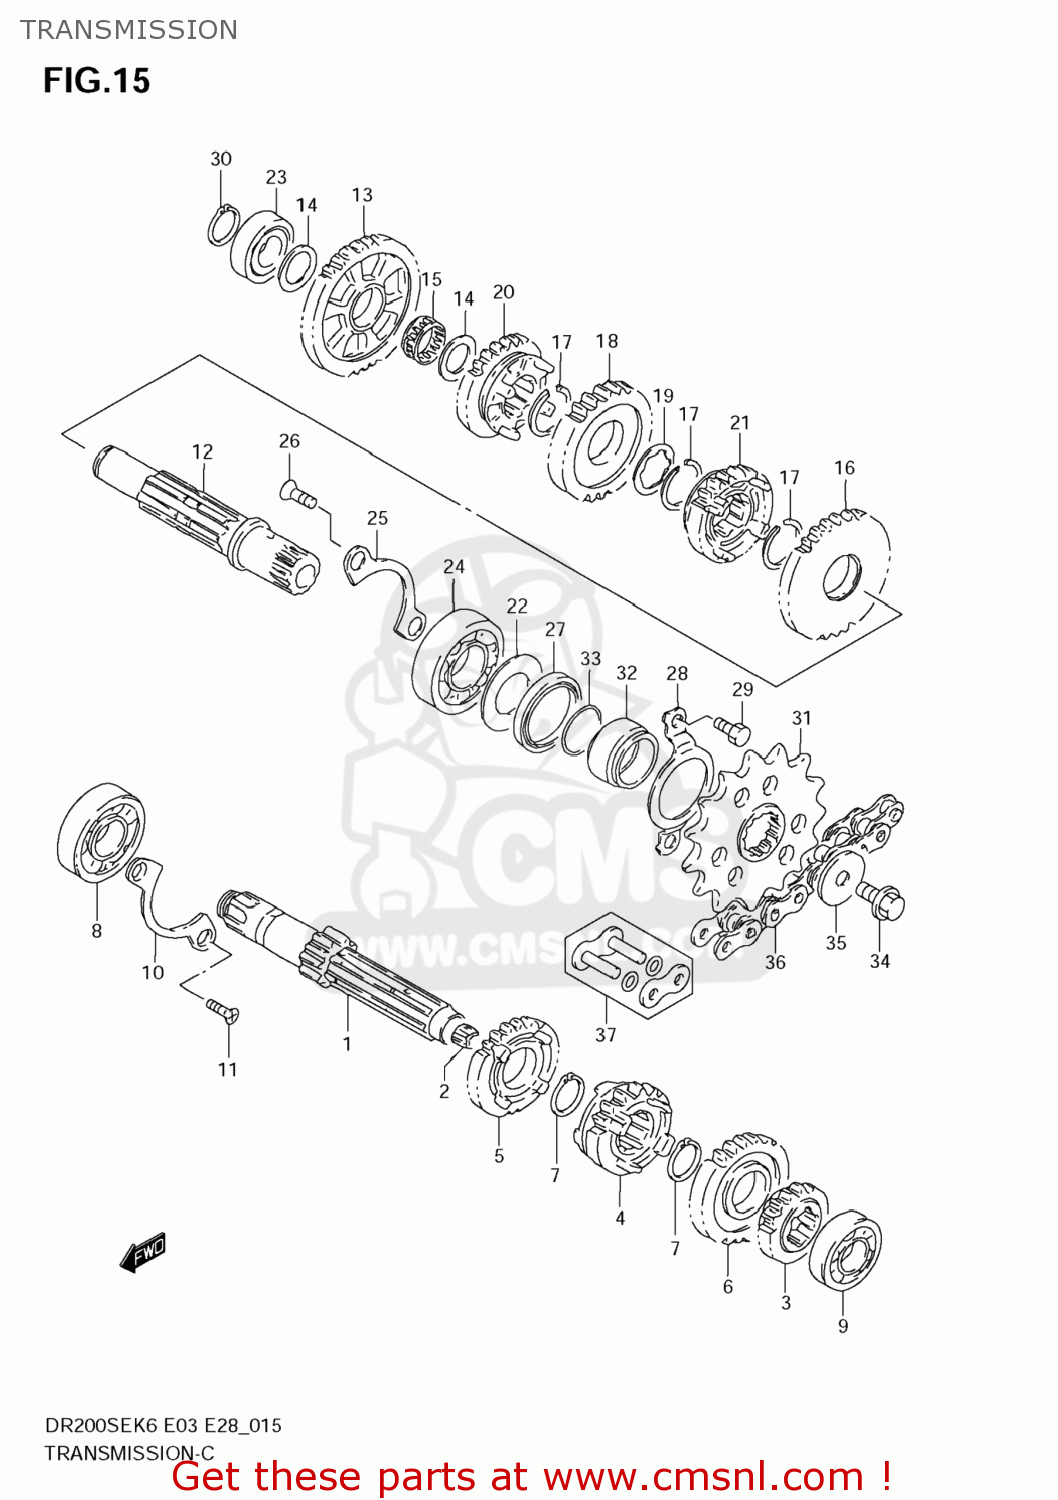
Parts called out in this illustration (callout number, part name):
1	SHAFT,COUNTER
2	BUSH
3	GEAR,2ND DRIVE
4	GEAR,3RD DRIVE(NT:16)
5	GEAR,4TH DRIVE
6	GEAR,FIFTH DRIVE
7	CIRCLIP
8	BEARING(20X47X14)
9	BEARING
10	RETAINER,DRIVE SHAFT BEARING
11	SCREW
12	SHAFT,DRIVE
13	GEAR,1ST DRIVEN
14	SHIM(17X26X1)
15	BEARING(17X21X9.8)
16	GEAR,2ND DRIVEN(NT:29)
17	CIRCLIP
18	GEAR,3RD DRIVEN(NT:23)
19	WASHER,LOCK
20	GEAR,4TH DRIVEN(NT:23)
21	GEAR,5TH DRIVEN
22	WASHER,OIL SEALING
23	BEARING(17X36X12)
24	BEARING(22X50X14)
25	RETAINER,DRIVE SHAFT BEARING
26	SCREW
27	SEAL,OIL(30X40X6)
28	RETAINER,DRIVE SHAFT OIL SEAL
29	BOLT
30	CIRCLIP
31	SPROCKET,ENGINE
32	SPACER,ENGINE SPROCKET
33	O RING(D:2.5,ID:21)
34	BOLT
35	WASHER
36	CHAIN(DID520VC5,112LE)
37	JOINT SET,CHAIN
